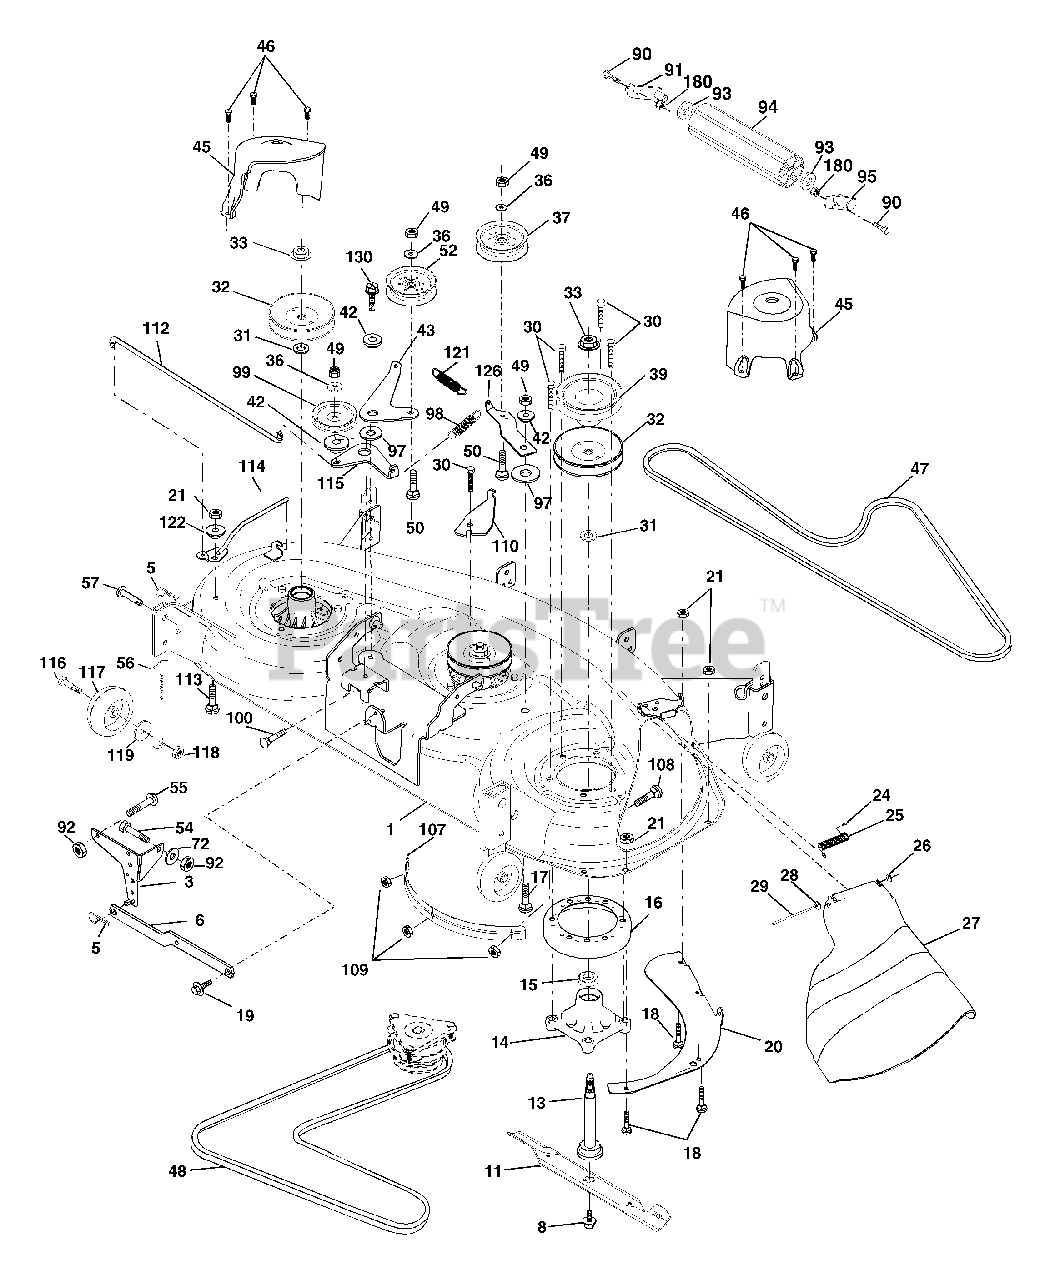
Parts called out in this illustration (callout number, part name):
1	Deck Weldment Mower 48
3	Bracket Asm., Sway Bar
5	Retainer Spring
6	Arm, Suspension, Rear (Sway Bar)
8	Bolt 7/16 Asm. Blade
11	Blade
13	Shaft Asm. w/Lower Bearing
14	Mandrel Asm.
15	Bearing, Ball, Mandrel
16	Stripper Mandrel Deck
17	Bolt RDHD Sq Neck 3/8-16 x 1.25
18	Bolt, Carriage 5/16-18 x 5/8
19	Bolt, Hex Hd, Shoulder 5/16-18
20	Baffle, Vortex Mower
21	Nut, Crownlock 5/16-18 UNC
24	Cap, Sleeve
25	Spring, Torsion
26	Nut, Push
27	Deflector Shield
28	Washer 11/32 x 5/8 x 16 Ga.
29	Rod,Hinge
30	Screw, Thdroll Washer Head
31	Washer, Spacer Mower Vented
32	Pulley, Mandrel
33	Nut, Flg. Top Lock Cntr. 9/16
36	Washer 13/32 x 13/16 x 16 Ga.
37	Pulley, Idler, Flat
39	Pulley, Idler, Driven
42	Spacer,Retainer
43	Arm, Idler Secondary
45	Cover, Mandrel Deck
46	Screw, Thdroll. 1/4-20 x 5/8
47	V-Belt, Mower, Secondary
48	V-Belt, Mower, Primary
49	Nut, Crownlock 3/8-16 UNC
50	Bolt, Carr. 3/8-16 x 1-1/2 Gr. 5
52	Pulley Idler Flat
56	Bar Pnt Adj.
57	Pin Head Rivet
90	Bolt Hex HD 5/16-18 x 1
91	Bracket Asm N Roller LH
93	Washer 17/32 x 7/8 x 16 Ga
94	Roller Nose 48"
95	Bracket Asm N Roller RH
97	Washer Hardened
98	Spring Primary Drive
99	Pulley Idler "V"
100	Bolt RDHD Sqnk 3/8-16 UNC x 2
107	Baffle Vac Edge Mower
108	Bolt Carr.
109	Nut Crownlock 1/4-20
110	Arm Spring Secondary
112	Link Tension Relief Lever
113	Bolt Carr. 5/16-18 x 1
114	Tension Asm. Relief Lever
115	Arm Spring Tension Relief
116	Bolt, Shoulder
117	Gauge Wheel
118	Nut, Centerlock 3/8-16 UNC
119	Washer 3/8 x 7/8 x 14 Ga.
121	Spring Secondary Drive
122	Bushing Pivot Tension Relief
126	Arm, Idler, Primary Deck
130	Screw 3/8-16 x 1.0
180	Nut Lock Hx 5/16-18
